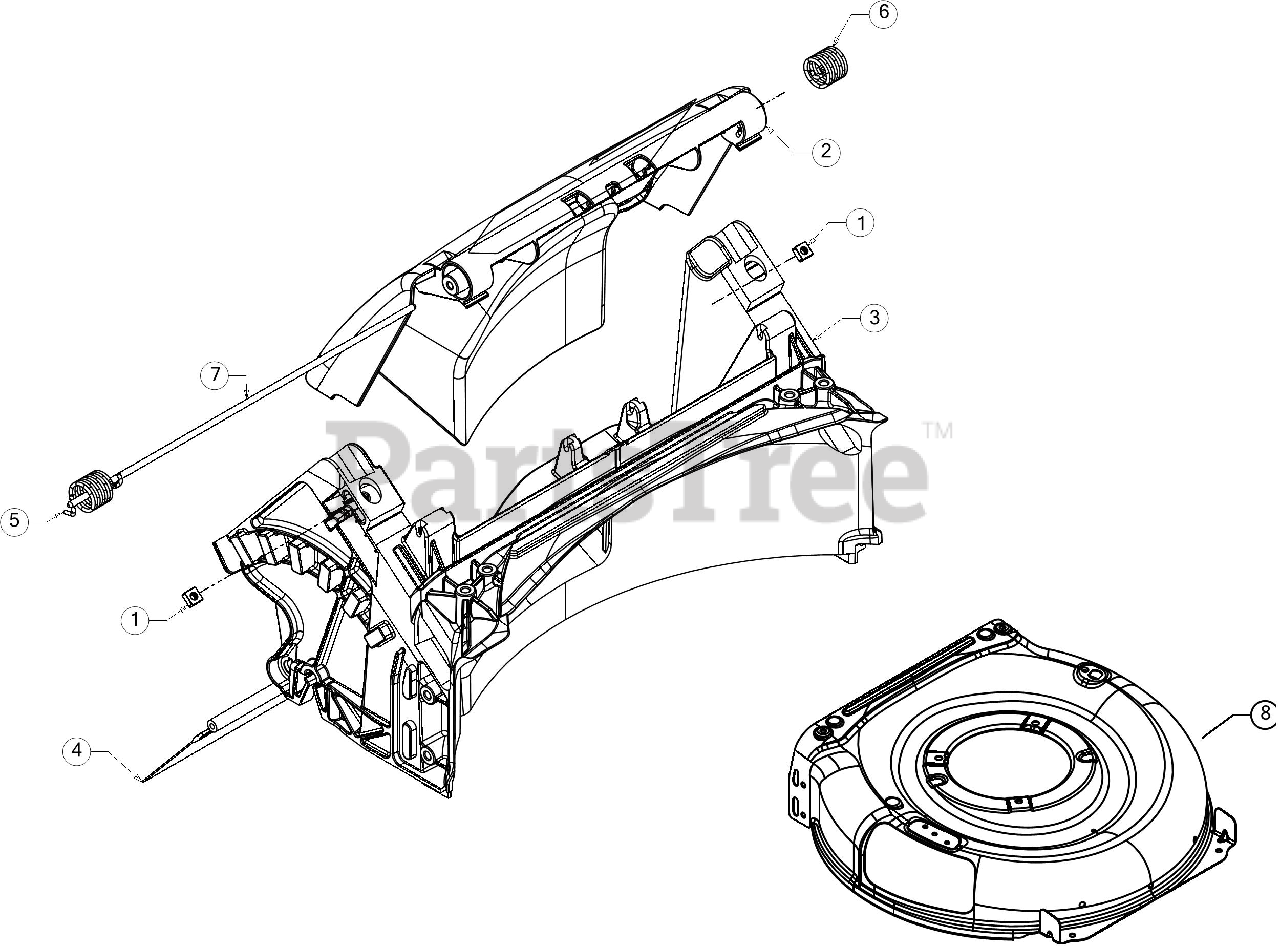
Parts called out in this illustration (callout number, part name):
1	SQUARE NUT 1/4-20
3	DOOR ASSEMBLY
4	TRAILSHIELD
5	TORSION SPRING (RH)
6	TORSION SPRING (LH)
7	REAR DOOR PIVOT ROD
8	21" DECK (3N1)
